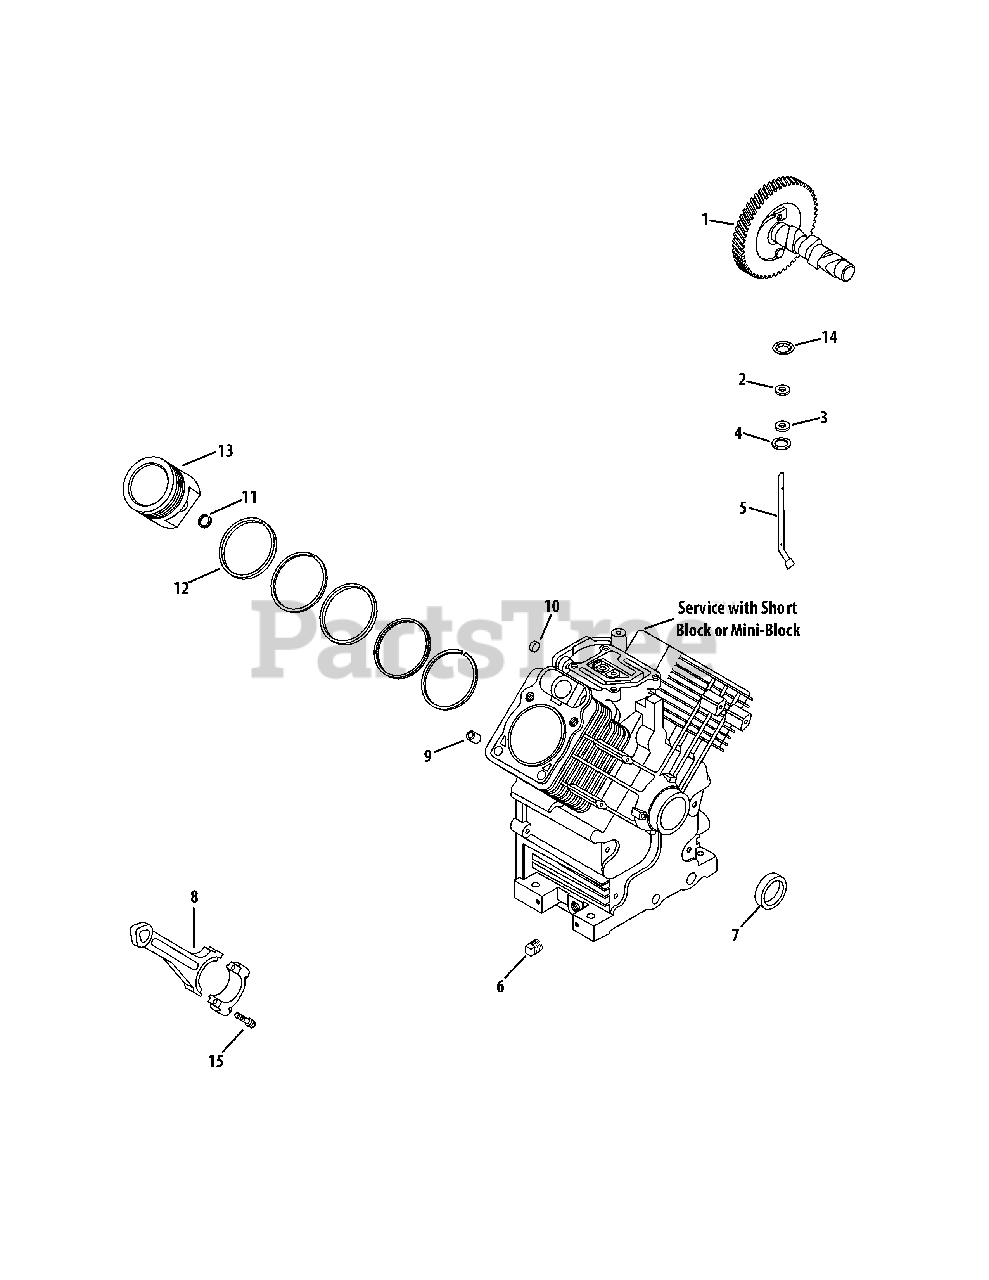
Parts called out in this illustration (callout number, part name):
1	Camshaft Kit
2	Flat Washer, 9 MM
3	Governor Cross Shaft Seal
4	Flat Washer, 11/32
5	Governor Cross Shaft
6	Square Headd Pipe Plug, 3/8
7	Oil Seal (Helix Lip)
8	Connecting Rod Assembly
11	Piston Pin Retainer
12	Ring Set (Std)
12	Ring Set (.08)
12	Ring Set (.25)
12	Ring Set (.50)
13	Piston Assembly Kit w/ Ring (Std.)
13	Piston Assembly Kit w/ Ring Set (.08)
13	Piston Assembly Kit w/Ring Set (.25)
13	Piston Assembly Kit w/ Ring Set (.50)
14	Ring Retainer
15	Rod Bolts Kit
